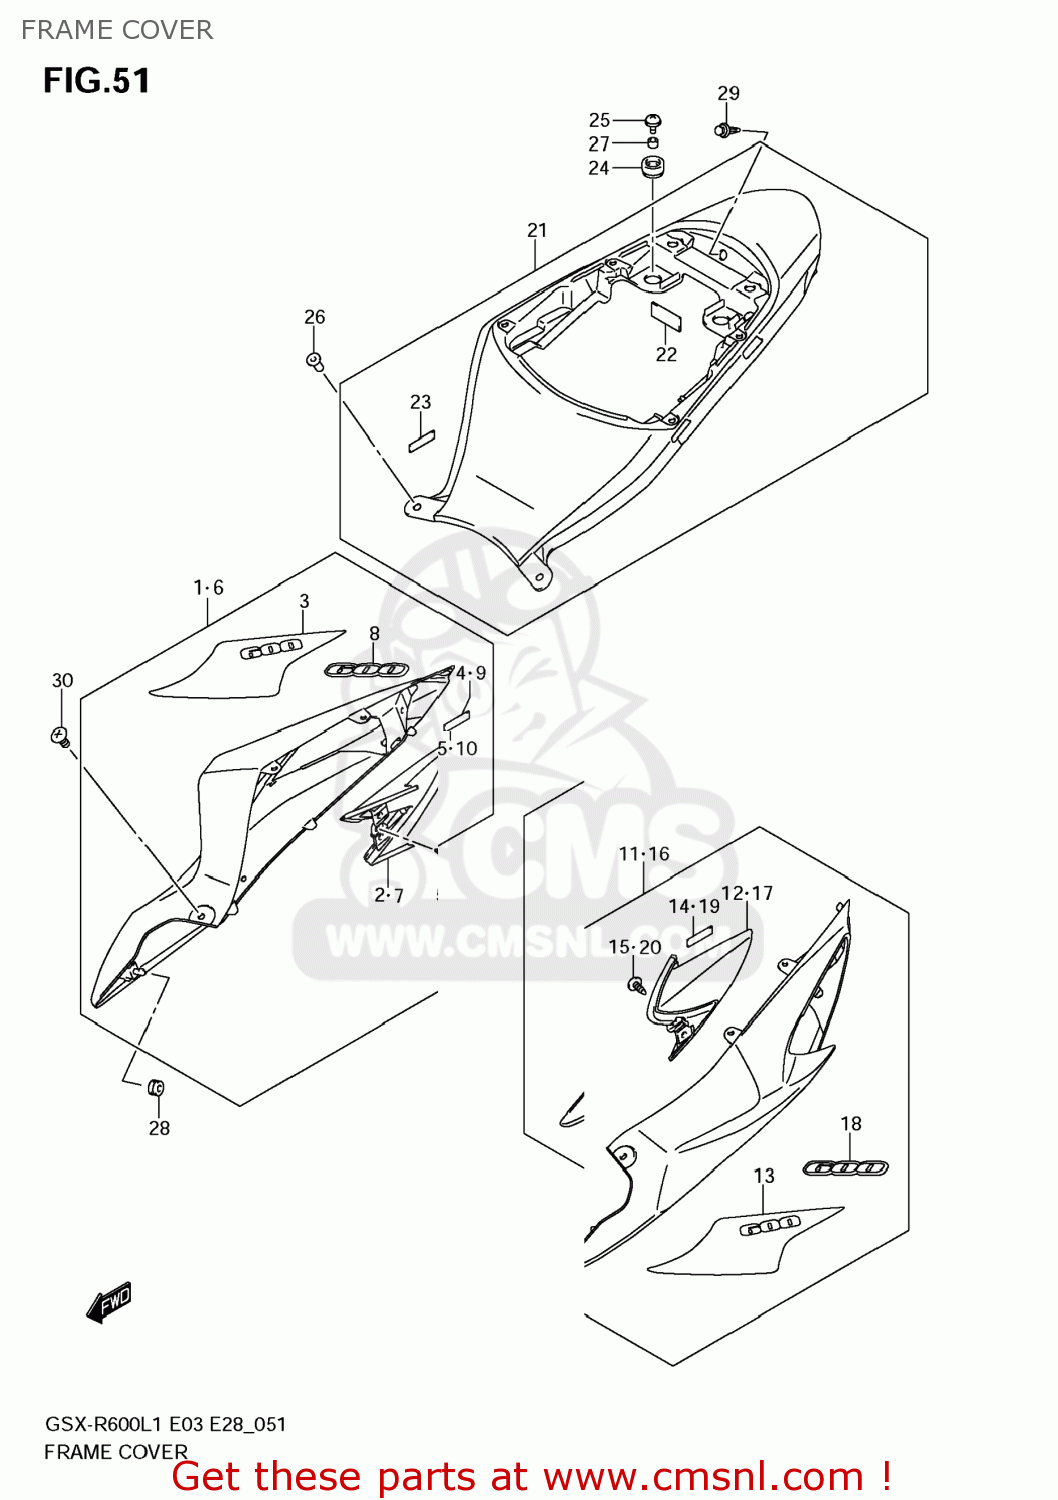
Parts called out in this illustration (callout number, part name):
1	COVER ASSY,FRAME,R(WHITE)
2	COVER,FRAME RR,R
3	TAPE,FRAME COVER,R
4	TAPE(6X25X0.13)
5	SCREW
6	COVER ASSY,FRAME,R(WHITE)
7	COVER,FRAME RR,R
8	EMBLEM,600
9	TAPE(6X25X0.13)
10	SCREW
11	COVER ASSY,FRAME,L(WHITE)
12	COVER,FRAME RR,L
13	TAPE,FRAME COVER,L
14	TAPE(6X25X0.13)
15	SCREW
16	COVER ASSY,FRAME,L(WHITE)
17	COVER,FRAME RR,L
18	EMBLEM,600
19	TAPE(6X25X0.13)
20	SCREW
21	COVER ASSY,FRAME CTR
22	CUSHION
23	TAPE(6X25X0.13)
24	CUSHION,FRAME COVER RR
25	SCREW(6X16)
26	NUT
27	SPACER(6.5X10X7)
28	CUSHION
29	CLIP(BLACK)
30	SCREW
